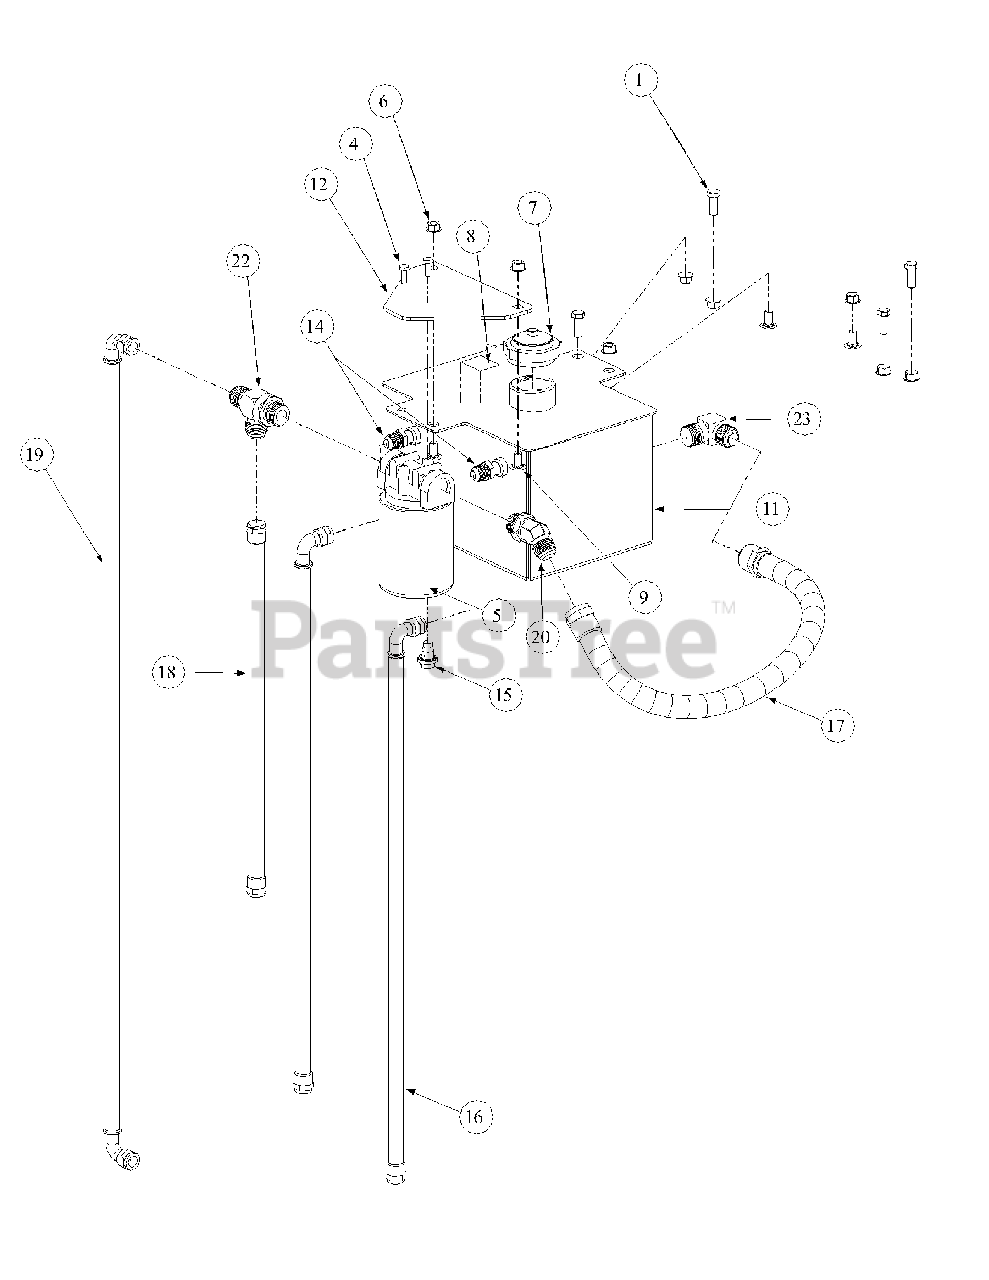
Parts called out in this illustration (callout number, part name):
1	Hex Cap Screw, 3/8-16, 1
3	Protective Hose Cover
4	Hex Cap Screw, 1/4-20, .75
5	Filter Head 3/4
5	33 Micron Filter
6	Hex Nut Flange Lock, 3/8-16
7	Cap, Hydro Oil Tank
8	Decal Oil Only 20W50
9	Carriage Bolt, 3/8-16 x .75 LG.
11	Hydraulic Tank Assembly
12	Mounting Plate Oil Filter
14	Fitting, 3/8 NPT, 1/2 Flare
15	Oil Pan Drain w/ Seal and Plug
16	Gearbox to Tank Hose Assembly
17	Tank to Filter Hose Assembly
18	Filter to Left Hand Pump Hose Assembly
19	Filter to Right Hand Pump Hose Assembly
20	Connector, 3/4 x3/4
22	Fitting Tee, 3/4 x 1/2 x 1/2
23	Fitting Elbow, 1/2 x 1/2
